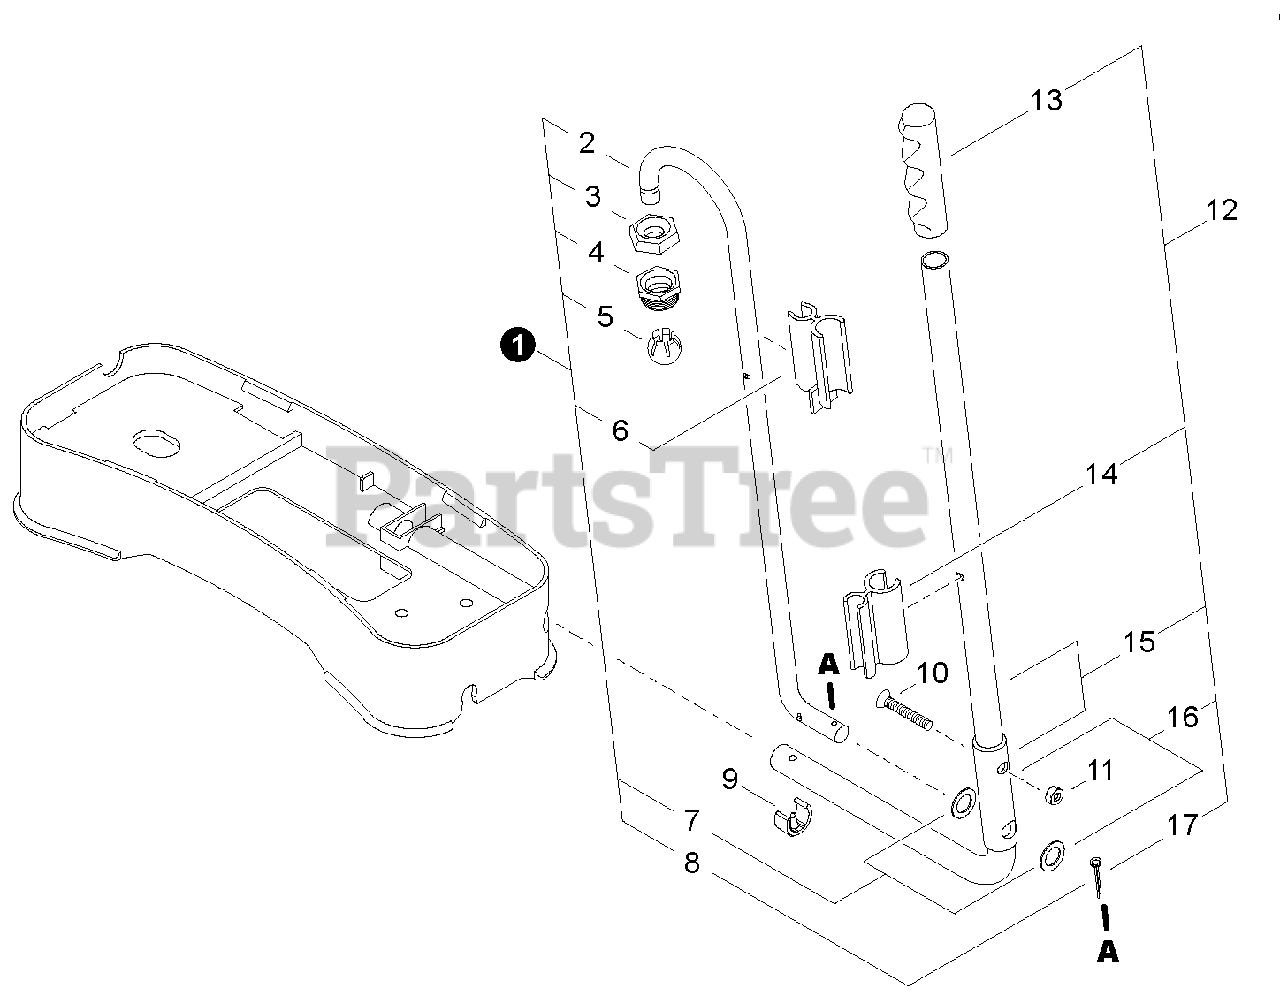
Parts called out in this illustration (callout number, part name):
1	PUMP ARM KIT
2	ARM, PUMP
3	BOOT, JOINT
4	NUT, JOINT
5	JOINT, BALL
6	CLIP, PUMP LEVER
7	WASHER
8	PIN, COTTER
9	C-CLIP
11	NUT, LOCK
12	LEVER KIT, PUMP
13	GRIP, LEVER
14	CLIP, WAND
15	LEVER, PUMP
16	WASHER
17	PIN, COTTER
